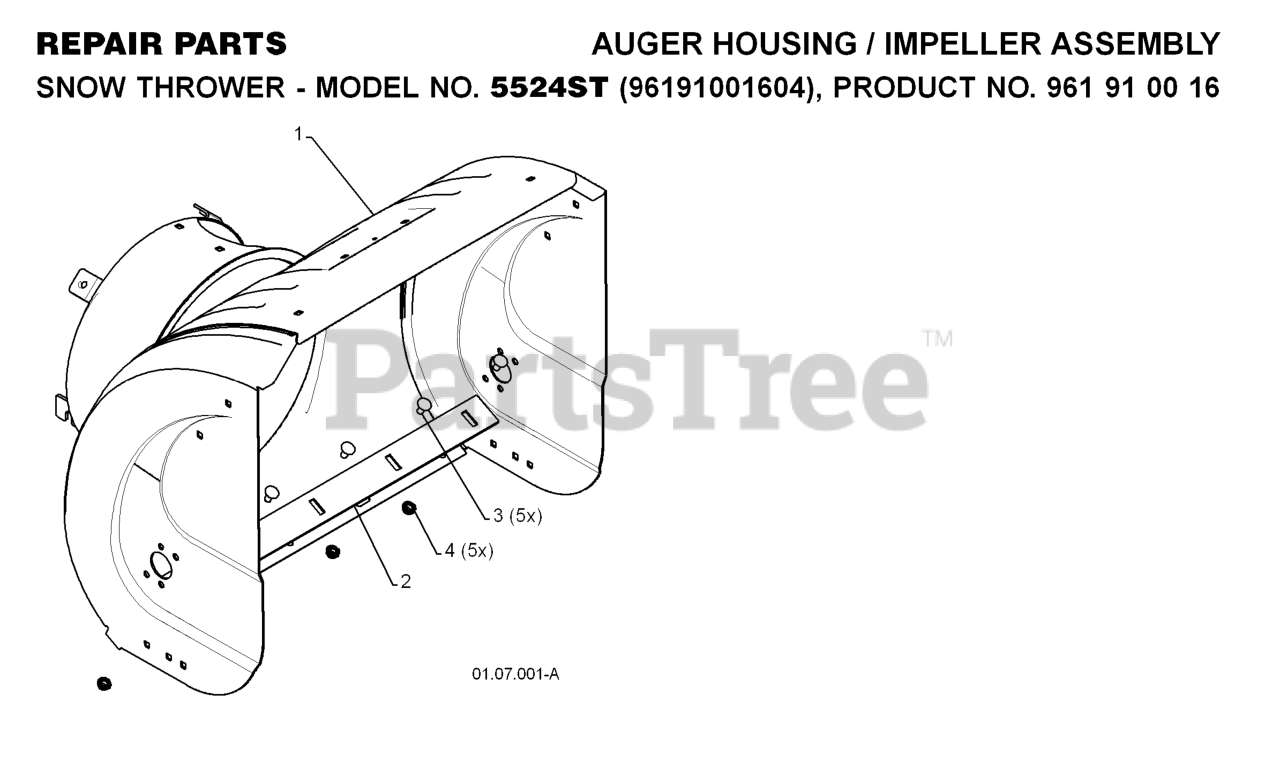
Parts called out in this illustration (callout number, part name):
1	AUGER HOUSING
2	BAR, SCRAPER
3	BOLT
4	NUT.FLANGE.5/16
